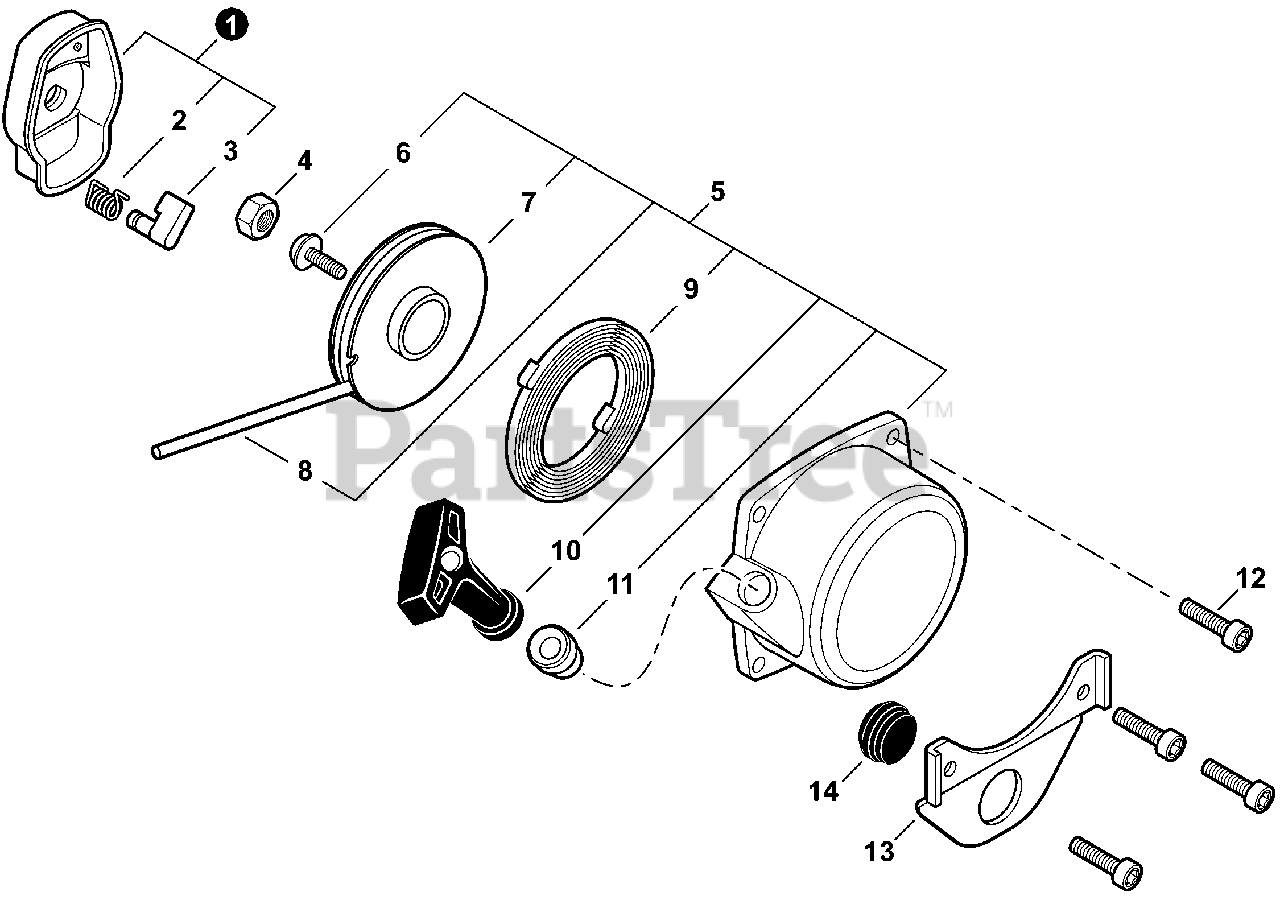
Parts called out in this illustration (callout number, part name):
1	PULLEY ASSY, STARTER
2	SPRING, RETURN
3	PAWL, STARTER - BLACK
5	STARTER ASSY, RECOIL
6	SCREW
7	REEL, ROPE
8	ROPE, STARTER 3.0×1000
9	SPRING, RECOIL
10	GRIP, STARTER
11	GUIDE, ROPE
12	BOLT, TORX 4×16
13	BRACKET, FUEL TANK
14	CUSHION
